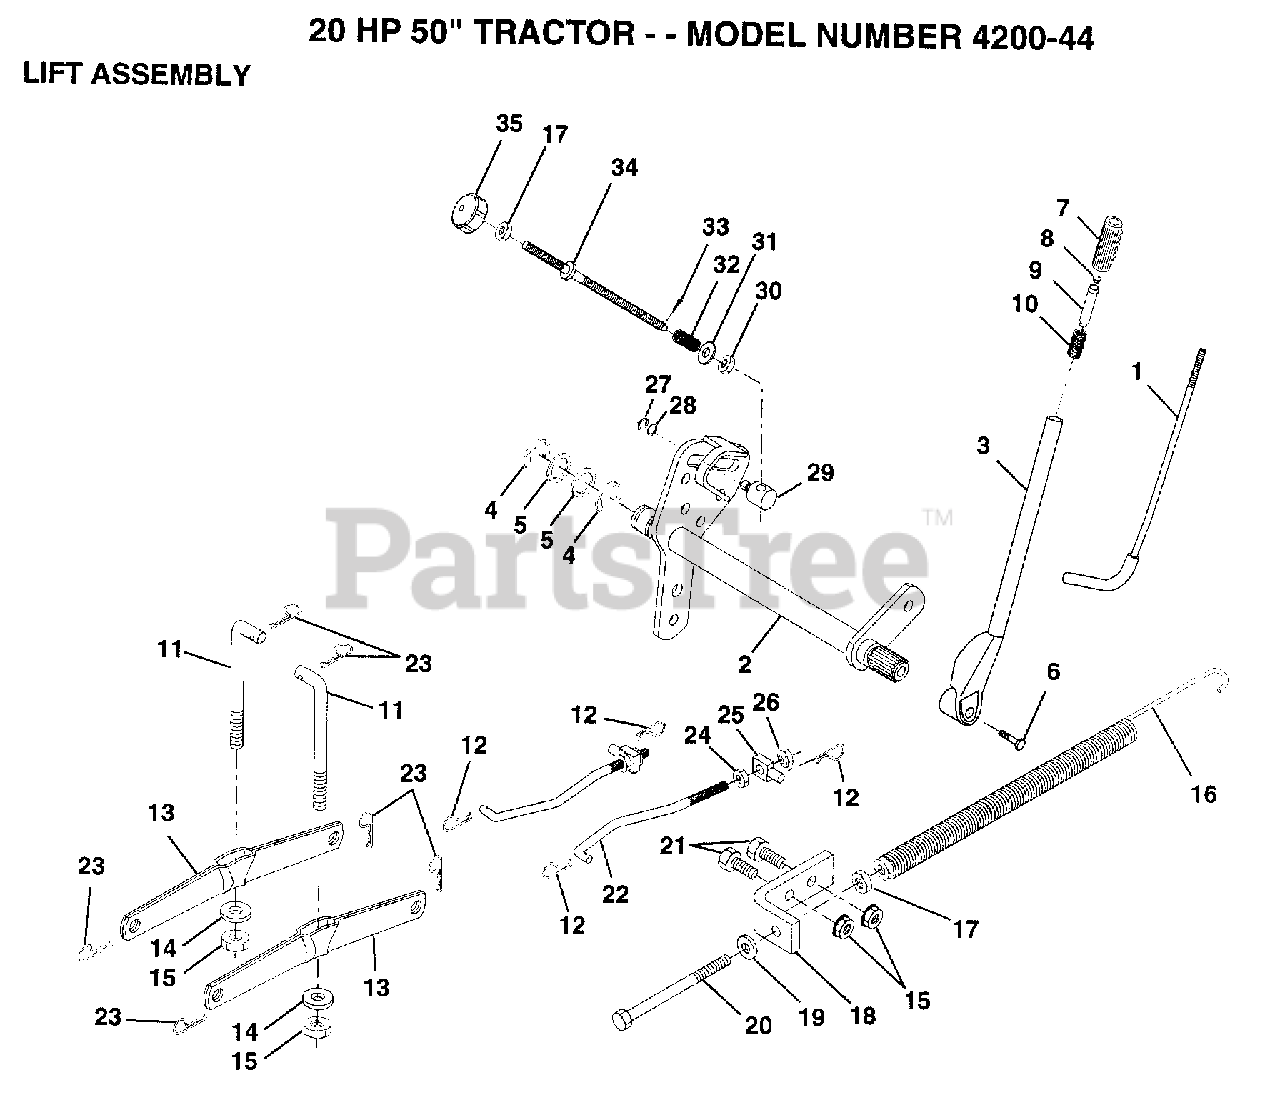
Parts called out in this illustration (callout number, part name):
1	LEVER ROD LT
4	E-RING
5	WASHER
6	"BOLT,HEX"
7	GRIP
10	SPRING T
12	RETAINER.SPRING
14	BEARING PVT LH
17	NUT
18	BRACKET SPRING AS
19	WASHER
20	BOLT-ADJ SPRING T
21	BOLT
22	LINK.FRONT
24	NUT
25	TRUNION
26	NUT.LK.W/WSH.1/2.
27	KLIP RING
28	WASHER
29	TRUNION LT
30	NUT T
31	WASHER
32	SPRING.COMP.INF.H
34	ROD.ADJ.LIFT
35	KNOB INF 3/8-16
